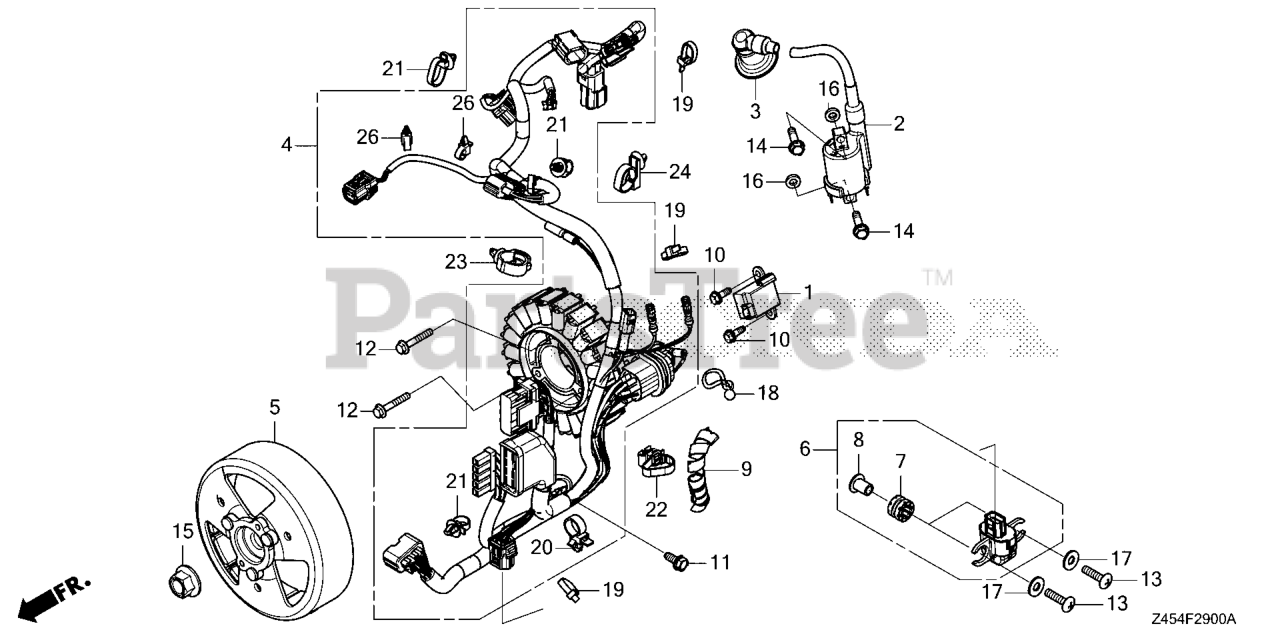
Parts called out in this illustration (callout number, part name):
1	GENERATOR ASSY., PULSE (TEC)
2	COIL COMP, IGN
3	CAP NOISE SUPPRESSOR
4	STATOR ASSY.
5	ROTOR COMP
6	SENSOR ASSY., BANK ANGLE
9	TUBE, SPIRAL B
10	BOLT, FLANGE (5X14) (CT200)
11	BOLT, FLANGE (6X14)
12	BOLT, FLANGE (5X32) (CT200)
13	SCREW (6X25) (NOT AVAILABLE)
14	BOLT, FLANGE (6X25) Use up to Engine SN 2056819.
15	NUT, FLANGE (14MM)
16	WASHER, PLAIN (6.5X15)
17	WASHER, PLAIN (7MM)
18	CLIP, PURSE LOCK
19	BAND, WIRE HARNESS
20	CLIP B, HARNESS BAND (129.4MM) (DARK BROWN)
21	CLIP, HARNESS BAND (145MM) (BLACK)
22	CLIP, HARNESS BAND (140.3MM) (BLACK)
23	CLIP, WIRE HARNESS *NH1L* (BLACK)
24	BAND, HARNESS OFFSET (10) (122.5MM) (BLUE)(W/SEAL)
26	TIE, CABLE
